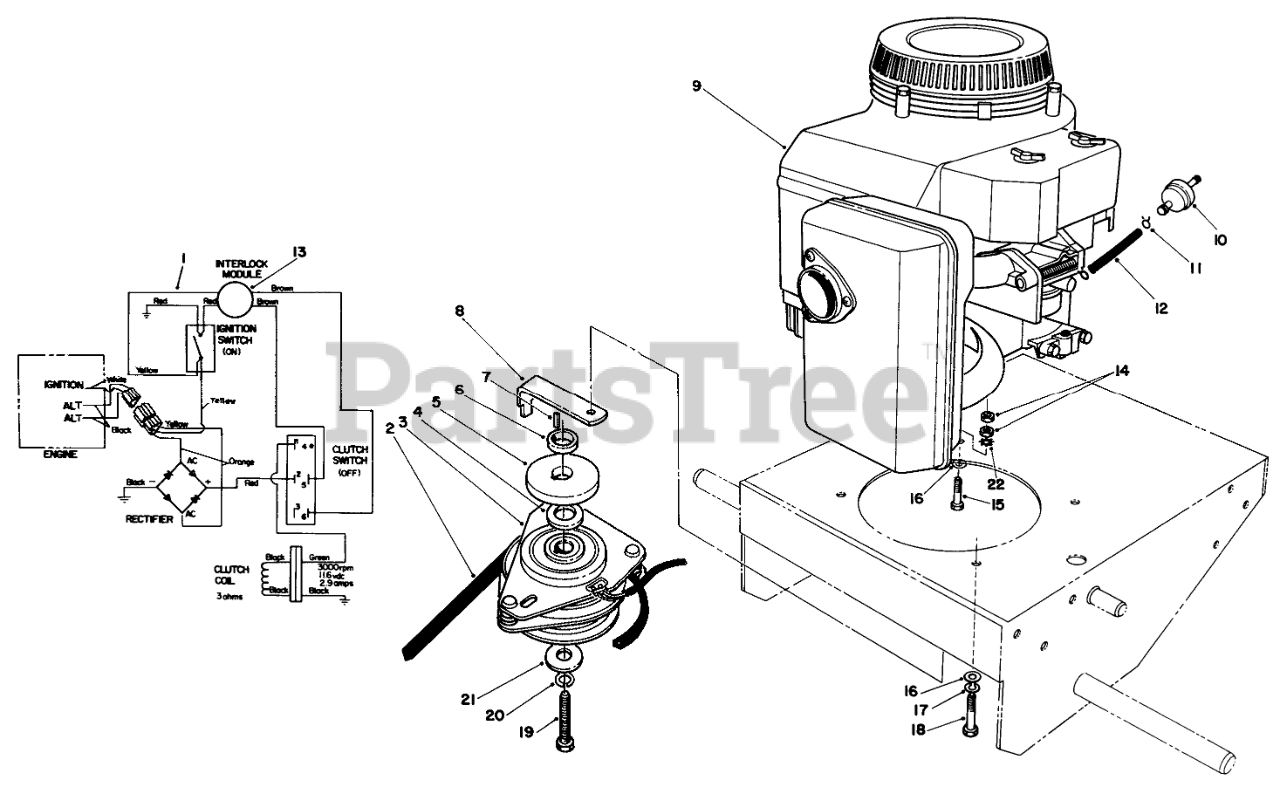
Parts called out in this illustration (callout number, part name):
1	WIRE HARNESS
2	V-BELT, DRIVE
3	CLUTCH/BRAKE
4	SPACER-LOWER
5	Pulley-Drive
6	Spacer-Upper
7	KEY-SQUARE
8	Retainer-Clutch
10	FILTER-FUEL
11	CLAMP-HOSE
12	HOSE-FUEL
13	Module
14	NUT-JAM
15	SCREW (ENGINE, GROUND)
16	WASHER-PLAIN
17	WASHER-LOCK
18	SCREW-HH
19	SCREW-CLUTCH
20	WASHER-LOCK
21	WASHER-CLUTCH
22	WASHER-LOCK
